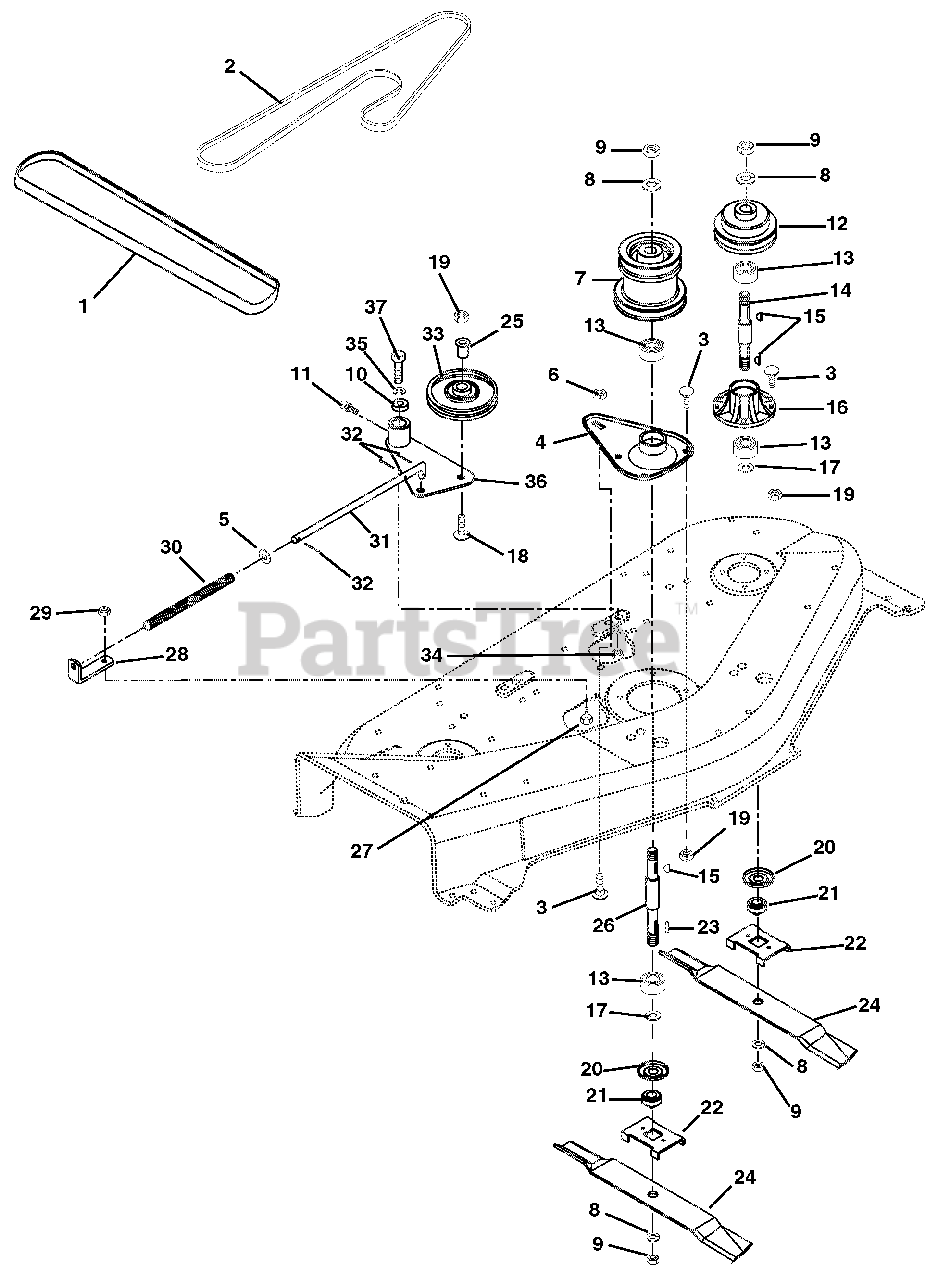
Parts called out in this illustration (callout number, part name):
1	Belt, 48" Clutch to Deck
2	Belt, 48" Deck
3	Bolt-Round Head Square Neck .38-16 x .75 Grade 5
4	Housing, Spindle
5	Washer-Flat-Steel .406 x .812 x .065
6	Nut-Locking-Center .38-16
7	Sheave, 48" Deck
8	Washer-Lock .750 x .188
9	Nut-Jam .75-10
10	Spacer, Pivot
11	Fitting, Lube .25-28 x .256
13	Bearing-Ball .75 x 1.78 x .61
14	Spindle Shaft
15	Key-Woodruff .188 x .62 x .25
16	Spindle Housing
17	Washer-Flat-Steel .754 x 1.000 x .032
18	Bolt-Button Head .38-16 x 1.25 Grade 5
19	Nut-Locking-Top-Flange .38-16
20	Bearing Slinger
21	Retainer Hub
22	Blade Tray 48
23	Key-Square .188 x .625 x .188
25	Spacer-Flanged .390 x .500 x .781 x .875
26	Spindle Shaft
27	Bolt-Hex .31-18 x .50 Grade 5
29	Nut-Locking-Top-Flange .31-18
30	Spring-Compression .106 x .63 x 12.0
31	Rod-Idler Spring
32	Pin-Cotter .09 x .75
33	Idler-Plastic 4.75 OD x .50 ID
34	Nut-Locking-Top-Flange .50-13
35	Washer-Flat-Steel .505 x .880 x .072
36	Idler Arm w/Zerk
37	Bolt-Hex .50-13 x 2.75 Grade 5
